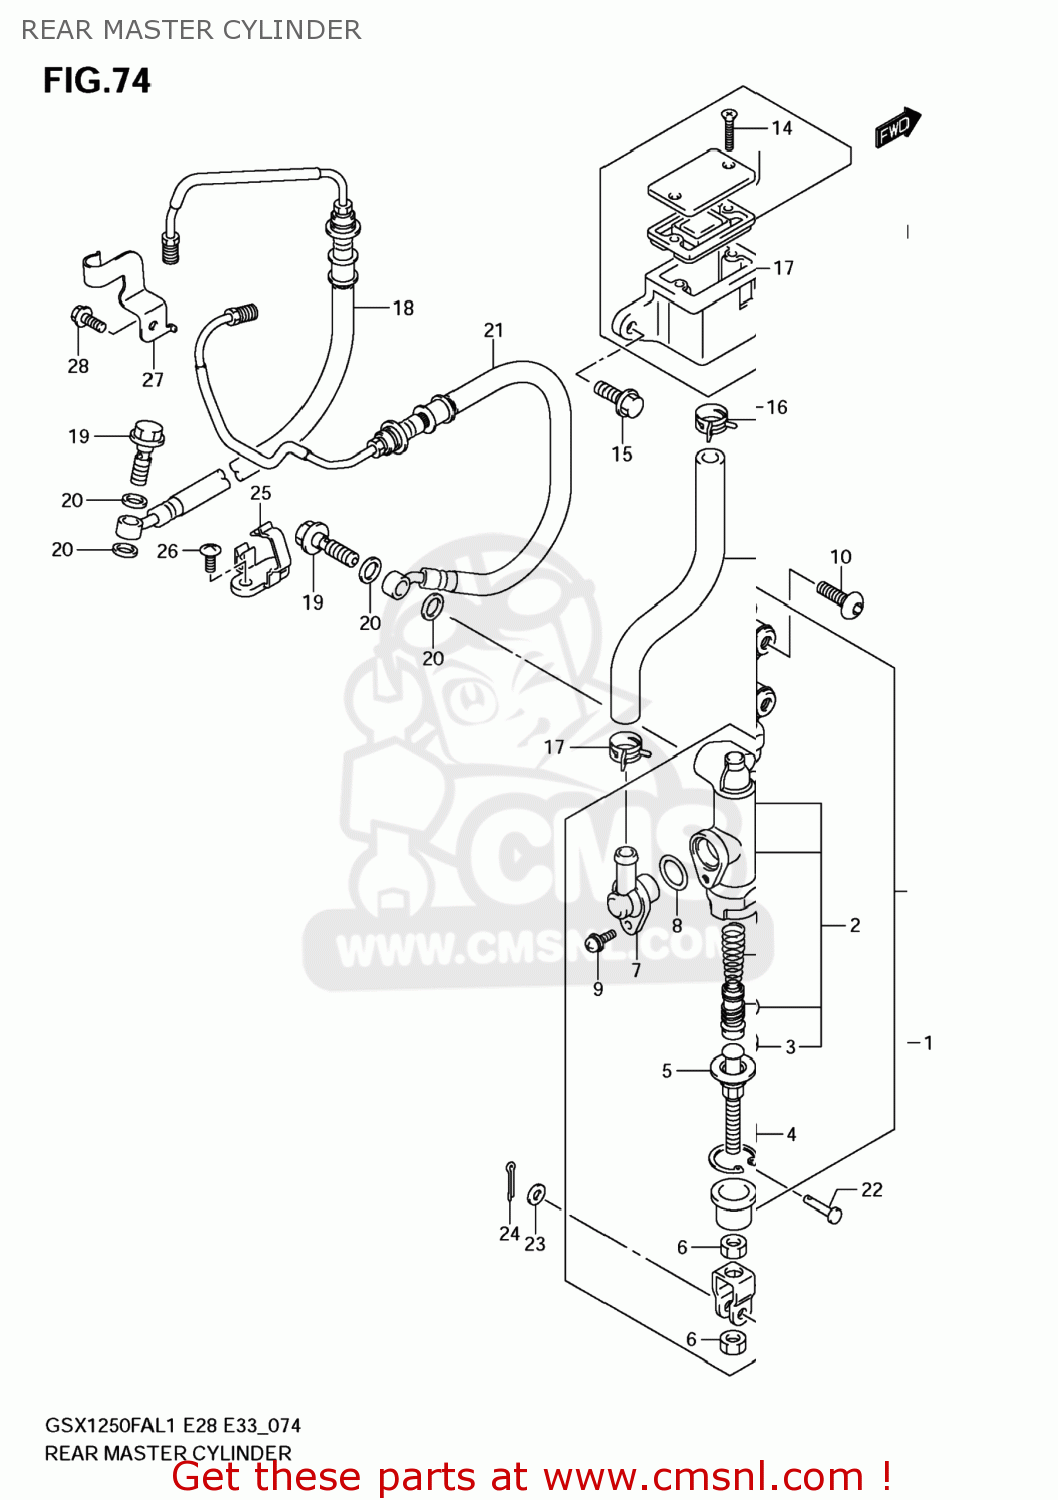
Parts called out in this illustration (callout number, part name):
1	CYLINDER ASSY,RR MASTER
2	PISTON/CUP SET
3	BOOT
4	YOKE
5	ROD,PUSH
6	NUT
7	CONNECTOR
8	O RING
9	SCREW
10	BOLT(8X20)
11	TANK ASSY,RESERVOIR
12	DIAPHRAGM
13	CAP
14	SCREW
15	BOLT
16	HOSE,RR RESERVOIR TANK
17	CLIP
18	HOSE ASSY,RR BRAKE NO.1
19	BOLT UNION
20	WASHER(10X15X1.5)
21	HOSE ASSY,RR BRAKE NO.2
22	PIN(6X18.2)
23	WASHER
24	PIN
25	GUIDE,RR BRAKE HOSE
26	SCREW
27	CLAMP,RR BRAKE HOSE NO.2
28	BOLT
